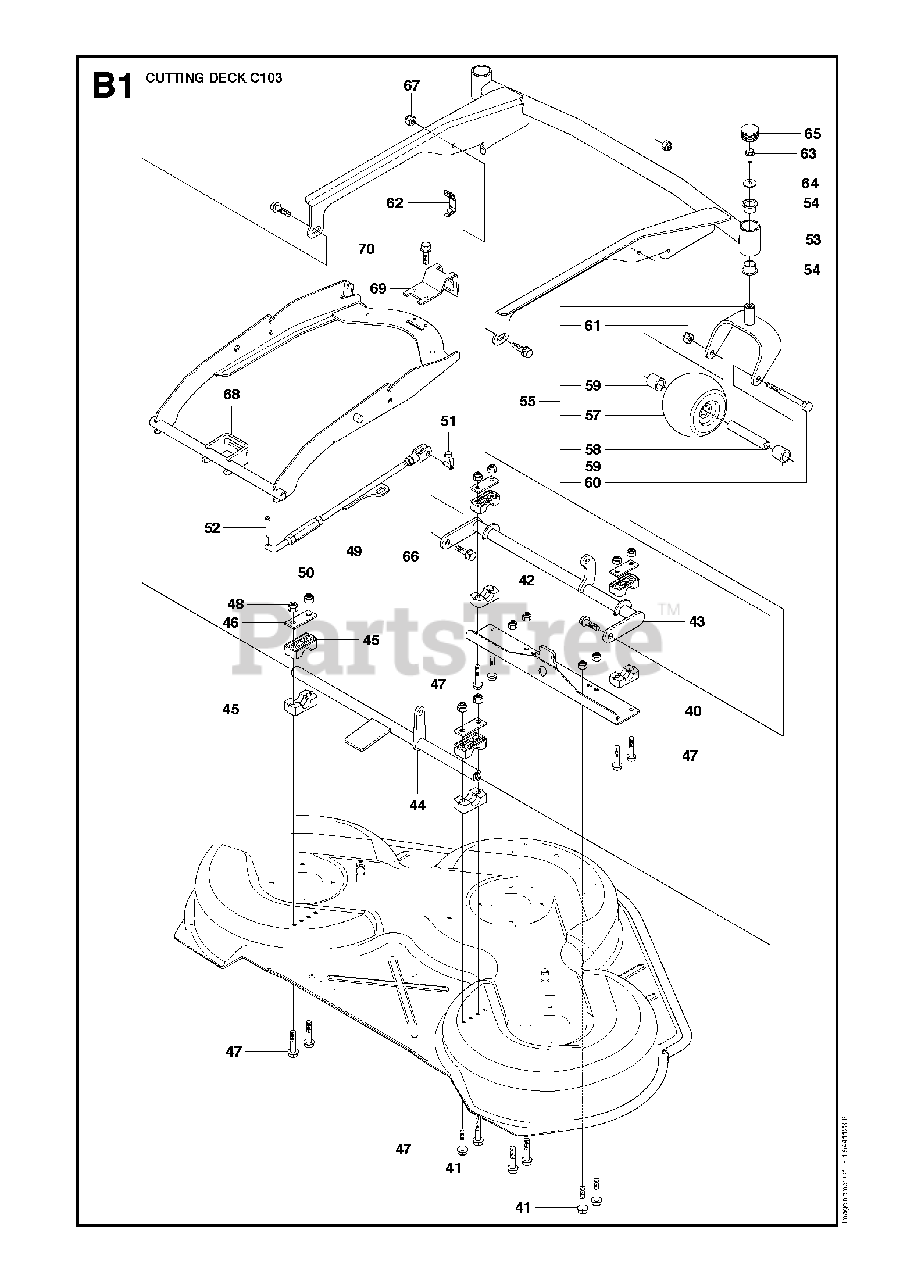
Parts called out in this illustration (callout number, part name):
42	LOCKNUT M8
48	LOCKNUT M8
49	PARALLELL ROD ASSY
50	PARALLEL ROD
51	RETAINER
53	DECK FRAME
55	PIVOT WHEEL ASSY
57	DECK ROLLER, FRONT
58	PIPE
59	SPACER
60	BOLT
61	NUT
62	CLIP GRAY
67	LOCKNUT M8
68	DECK ATTACHMENT
70	Screw
